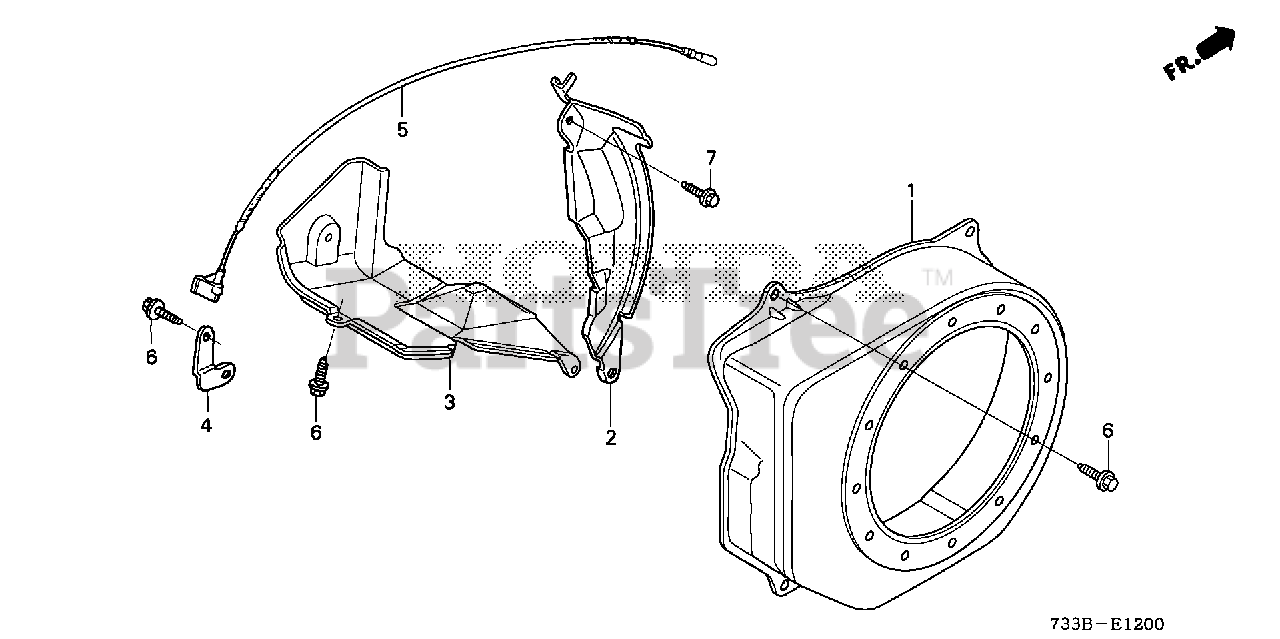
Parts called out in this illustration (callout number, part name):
1	COVER, FAN *R280* (POWER RED)
2	PLATE, SIDE (STD)
4	STAY, WIRE CLIP (B)
5	WIRE, STOP SWITCH (370MM)
5	WIRE, STOP SWITCH (370MM) (KOKUSAN)
6	BOLT, FLANGE (6X12) (CT200)
7	BOLT, FLANGE (6X20) (CT200)
